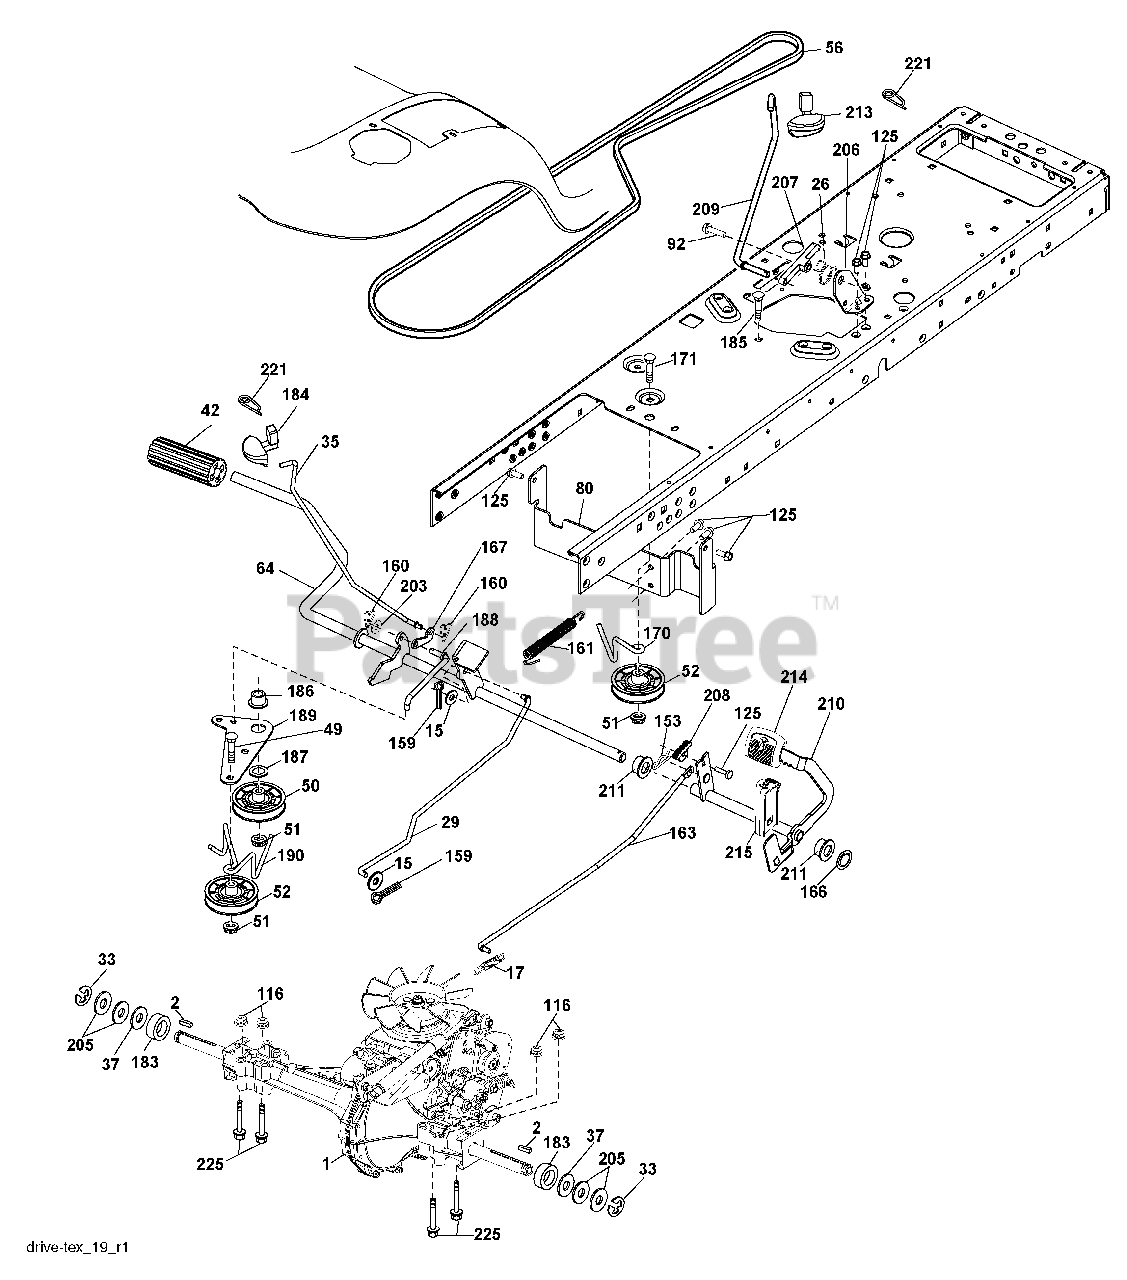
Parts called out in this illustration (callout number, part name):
2	Key
15	Washer 13/32 x 13/16 x 16 Ga.
17	Spring, Brake
26	Spring Return Cruise
29	Rod, Brake
33	Ring E
35	Rod, Brake, Park
37	Washer 25/32 x 1-1/4 x 16 Ga.
42	Cover, Foot Pedal
49	Bolt
50	Pulley Idler Flat
51	Lock Nut 3/8-16
52	Idler V-Groove 910" Offset
56	V-Belt, Drive
64	Shaft Asm. Pedal Brake Control
80	Bracket Strap Torque
92	Bolt Fin Hex 5/16-18 unc x 1.25
116	Nut Lock Hex Flange 5/16-18
125	Screw 5/16-18 x 3/4
153	Retainer Spring
159	Pin Cotter 1/8 x 3/4
160	Retainer Clip
161	Spring, Return, Clutch
163	Rod Pedal Control
166	Nut Push .625
167	Latch Brake Parking
170	Keeper Belt Centerspan
171	Bolt
183	Spacer Axle
184	Handle Parking Brake
185	Bolt
186	Spacer Retainer
187	Washer
188	Link Clutch Ground Drive
189	Bellcrank Ground Drive
190	Keeper Bellcrank Ground Drive
203	Washer 11/32 x 11/16 x 16 Ga.
205	Washer 25/32 x 1-5/8 x 16 Ga.
206	Bracket Mount Latch Cruise
207	Latch Control Cruise
208	Gear Sector Control Cruise
209	Rod Control Cruise
210	Rockr Asm. Pdeal Control
211	Bearing Nylon
213	Knob Control Cruise
214	Pad Pedal Forward
215	Pad Pedal Reverse
221	Retainer Spring Clip
225	Bolt Hex 5/16-18 x 3.75
